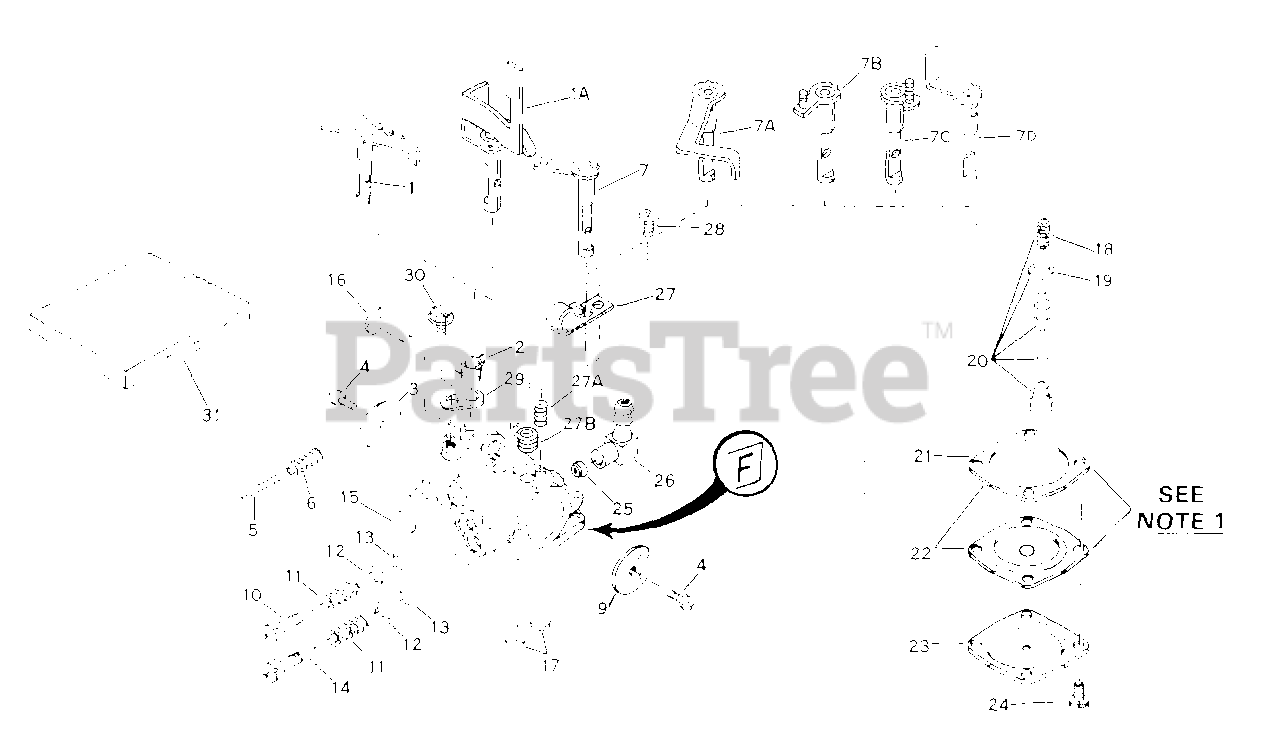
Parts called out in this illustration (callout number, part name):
1	"Shaft & Lever Assy., Throttle
2	Spring, Throttle return
3	Shutter, Throttle
4	Screw, Shutter
5	Screw, Idle regulating
6	Spring, Idle speed screw
7	Shaft & Lever Assy., Choke
9	Shutter, Choke
10	Screw, Idle adj
11	Spring, Adj. screw
12	Washer, Adj. screw
13	"O" Ring, Adj. screw
14	Screw, Main adj
15	Plug, Welch
16	Element, Pump
17	Plug, Welch
18	Spring, Valve
19	Gasket, Valve seat
20	Inlet Needle, Seat, Gasket & Spring A ssy.
21	Gasket, Diaphragm
22	Diaphragm Assy, (Incl. No. 21)
23	Cover, Diaphragm
24	Screw, Cover
25	Valve, Check
26	Fitting, Fuel line
27	Spring, Detent
29	Throttle shaft
31	Repair Kit
